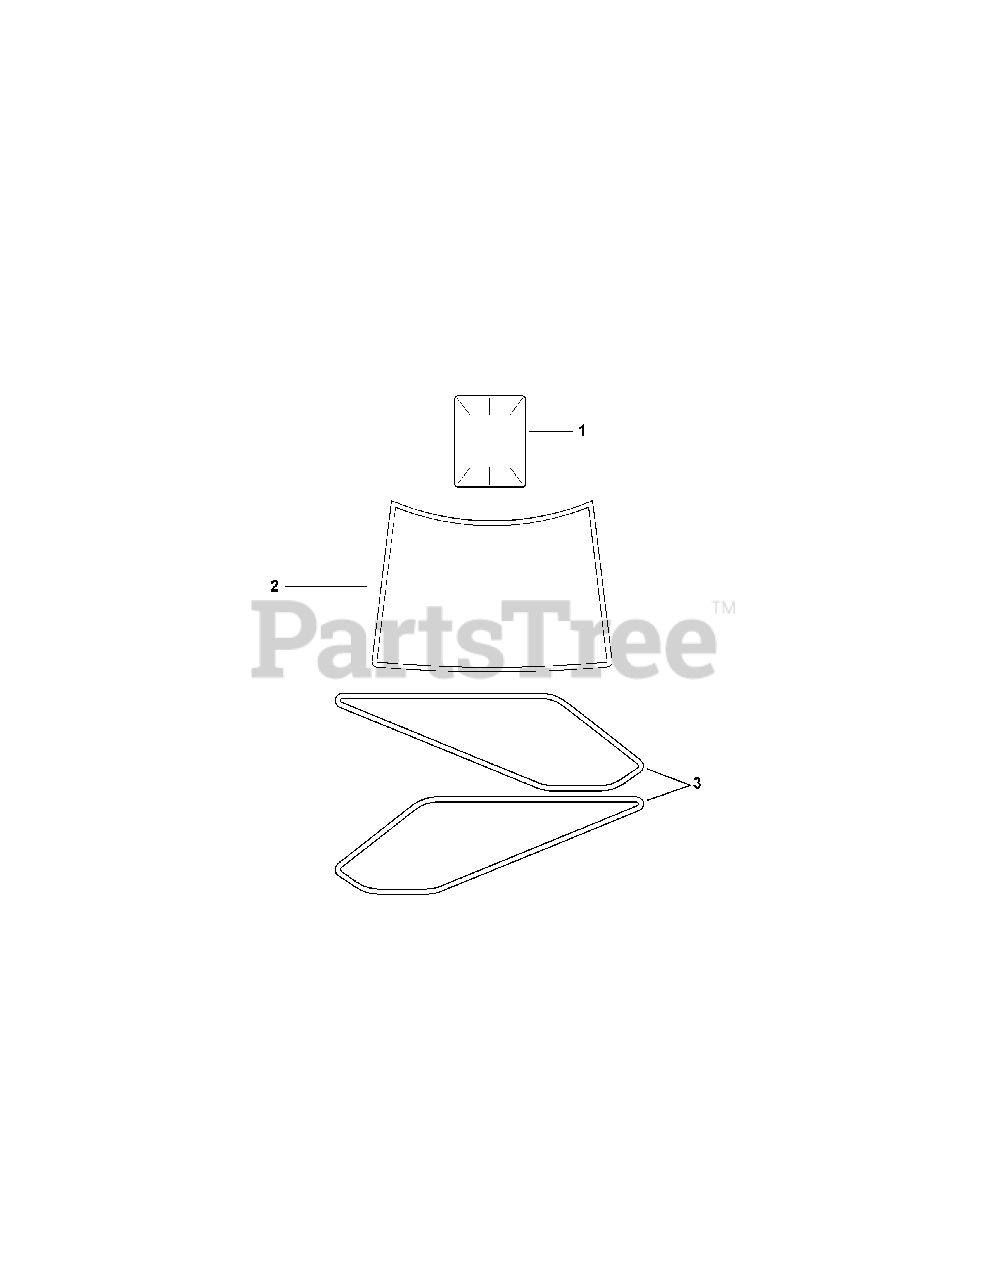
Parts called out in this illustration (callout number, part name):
1	Clear Laminate Decal
2	Decal, 20HP
3	Decal, Cub Twin Wings
